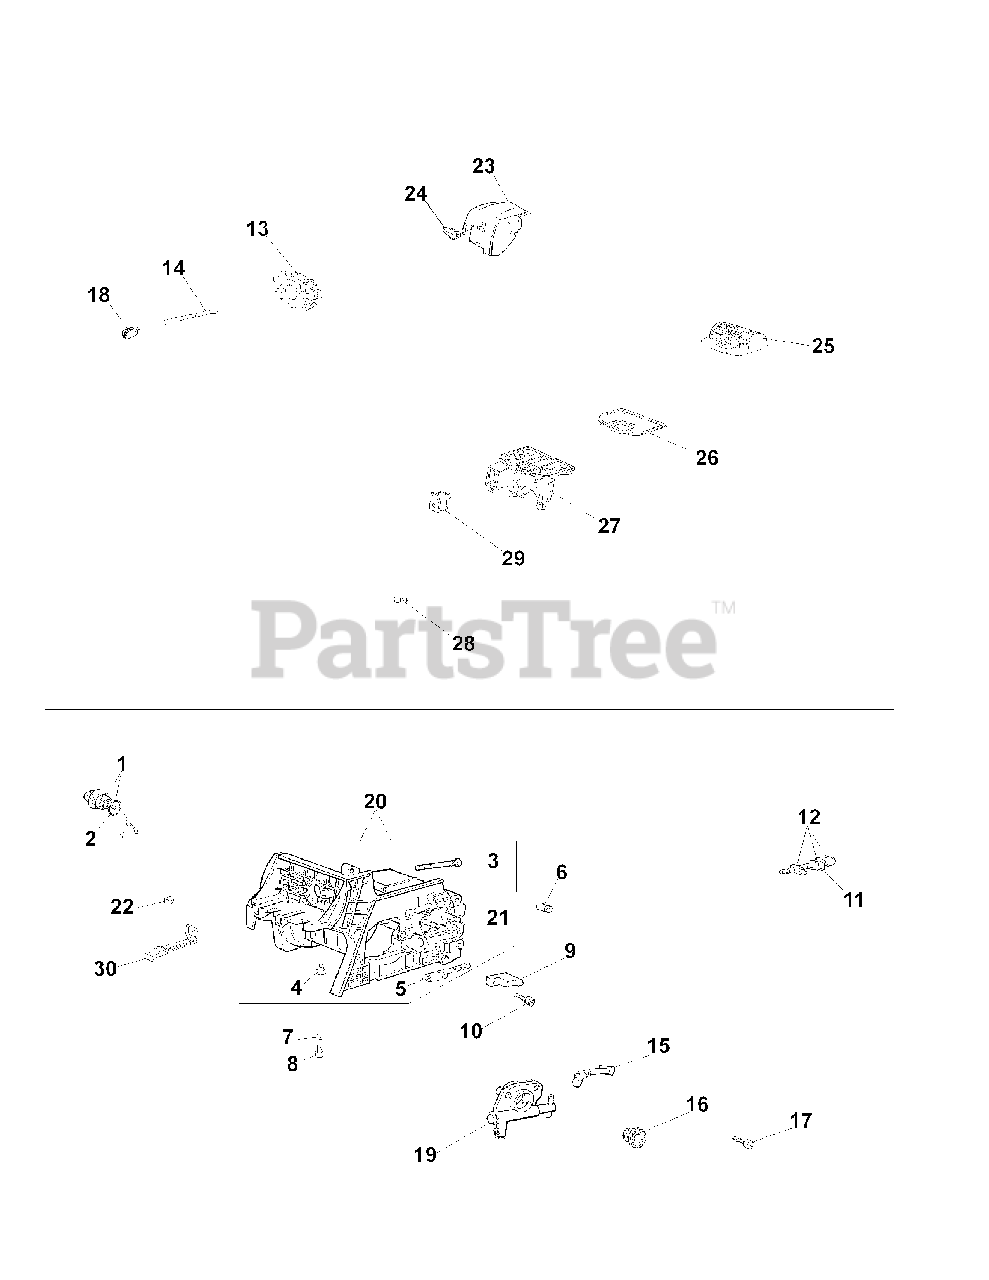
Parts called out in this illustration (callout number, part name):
9	CHAIN CATCHER
12	ADJUSTING SCREW
13	CARBURETOR
20	ENGINE BASE
23	AIR FILTER COVER
29	SWITCH
30	STARTER LEVER
